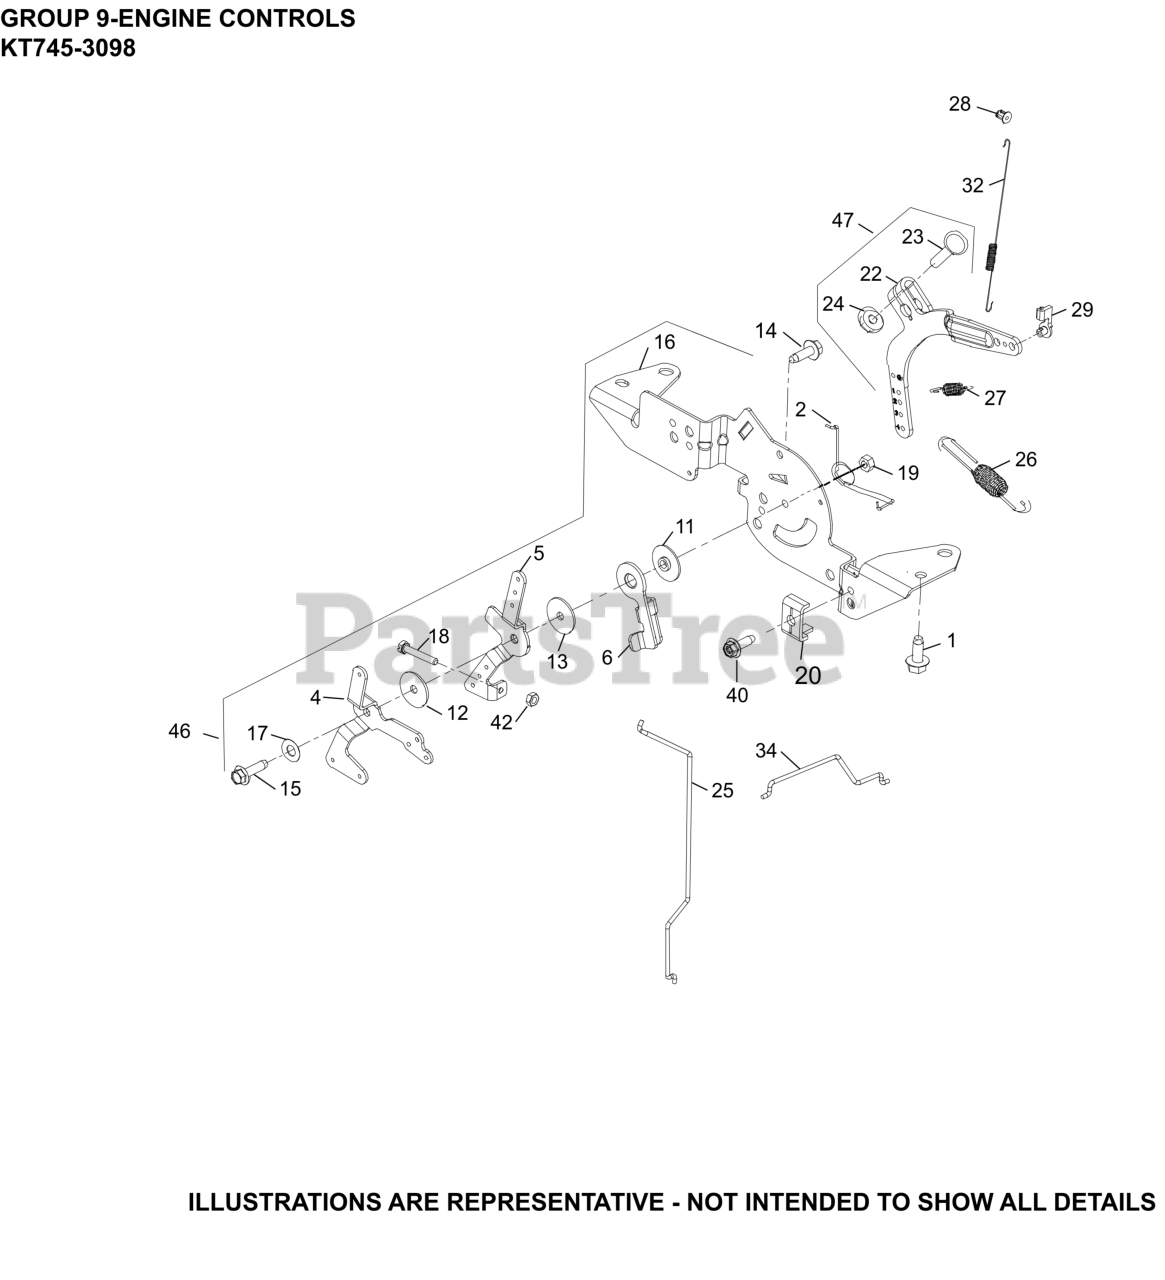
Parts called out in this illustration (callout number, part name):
1	SCREW, THREAD FORMING
2	SPRING, CHOKE RETURN
4	LEVER, CHOKE
5	LEVER, THROTTLE CONTROL
6	LEVER, THROTTLE ACTUATOR
11	SPACER, CONTROL ASSEMBLY
12	WASHER, FLAT 5.5 MM
13	WASHER, FLAT 5 MM
14	SCREW, THREAD FORMING
15	SCREW, THD FRM-USE 25 086 473-S
16	BRACKET, SPEED CONTROL
17	WASHER, SPRING 1/4"
18	SCREW, SLT HD CAP M4X0.7X25
19	NUT, LOCK M5X.8
20	CLAMP, CABLE CABLE
22	LEVER, GOVERNOR - (#2409069S)
23	BOLT, RD HD SQ NECK M6X1.0X25
24	NUT, FLG M6X1.0
25	LINKAGE, CHOKE
26	SPRING, GOVERNOR (ORANGE)
27	SPRING, GOVERNED IDLE
28	BUSHING, LINKAGE RETAINING
29	BUSHING, THROTTLE LINKAGE
32	SPRING, LINKAGE
34	LINKAGE, THROTTLE
40	SCREW, THREAD FORMING
42	NUT, M4X0.7
46	CONTROL ASSEMBLY, DUAL WIRE
47	LEVER, GOVERNOR ASSEMBLY
